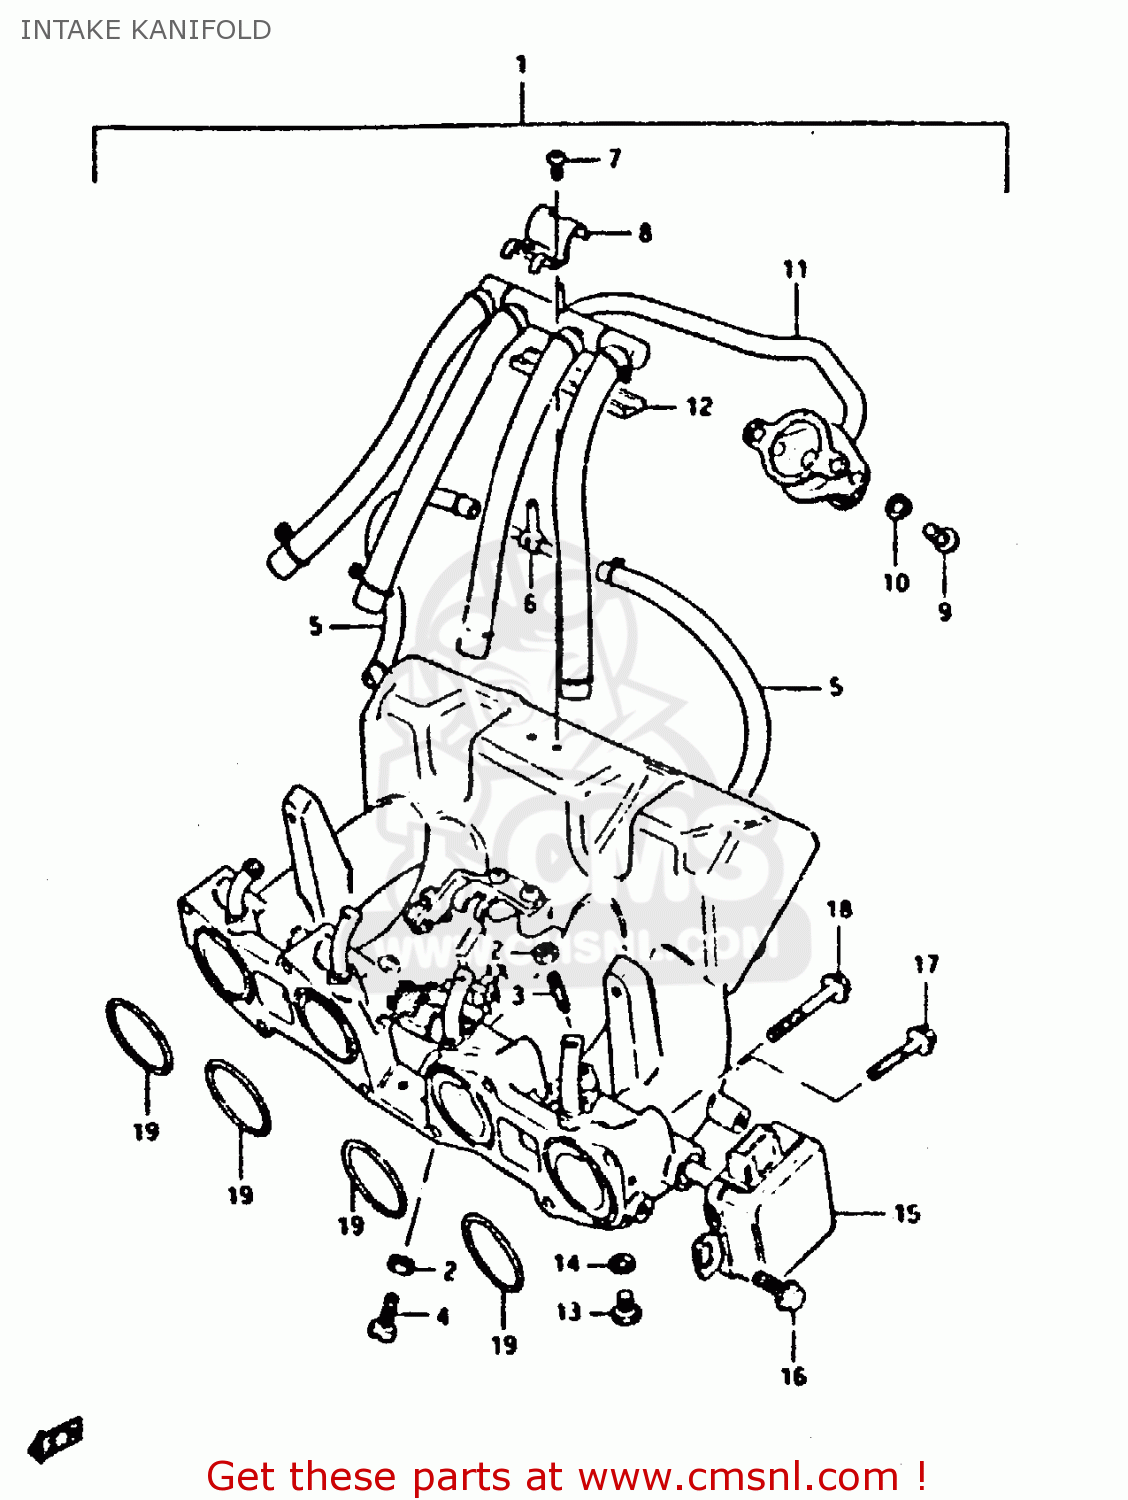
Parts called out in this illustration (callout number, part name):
1	MANIFOLD,INTAKE
2	NUT
3	SCREW
4	SCREW,THROTTLE ADJUST
5	HOSE
6	PIPE
7	SCREW
8	PLATE
9	SCREW 6X12
10	LOCK WASHER
11	SWITCH,CARBURETOR HEATER THERMOSTAT
12	SEAT, RUBBER
13	PLUG,DRAIN
14	WASHER,DRAIN PLUG
15	SENSOR ASSEMBLY,THROTLLE P
16	BOLT
17	BOLT
18	BOLT
19	O RING(D:2.4,ID:37.7)
